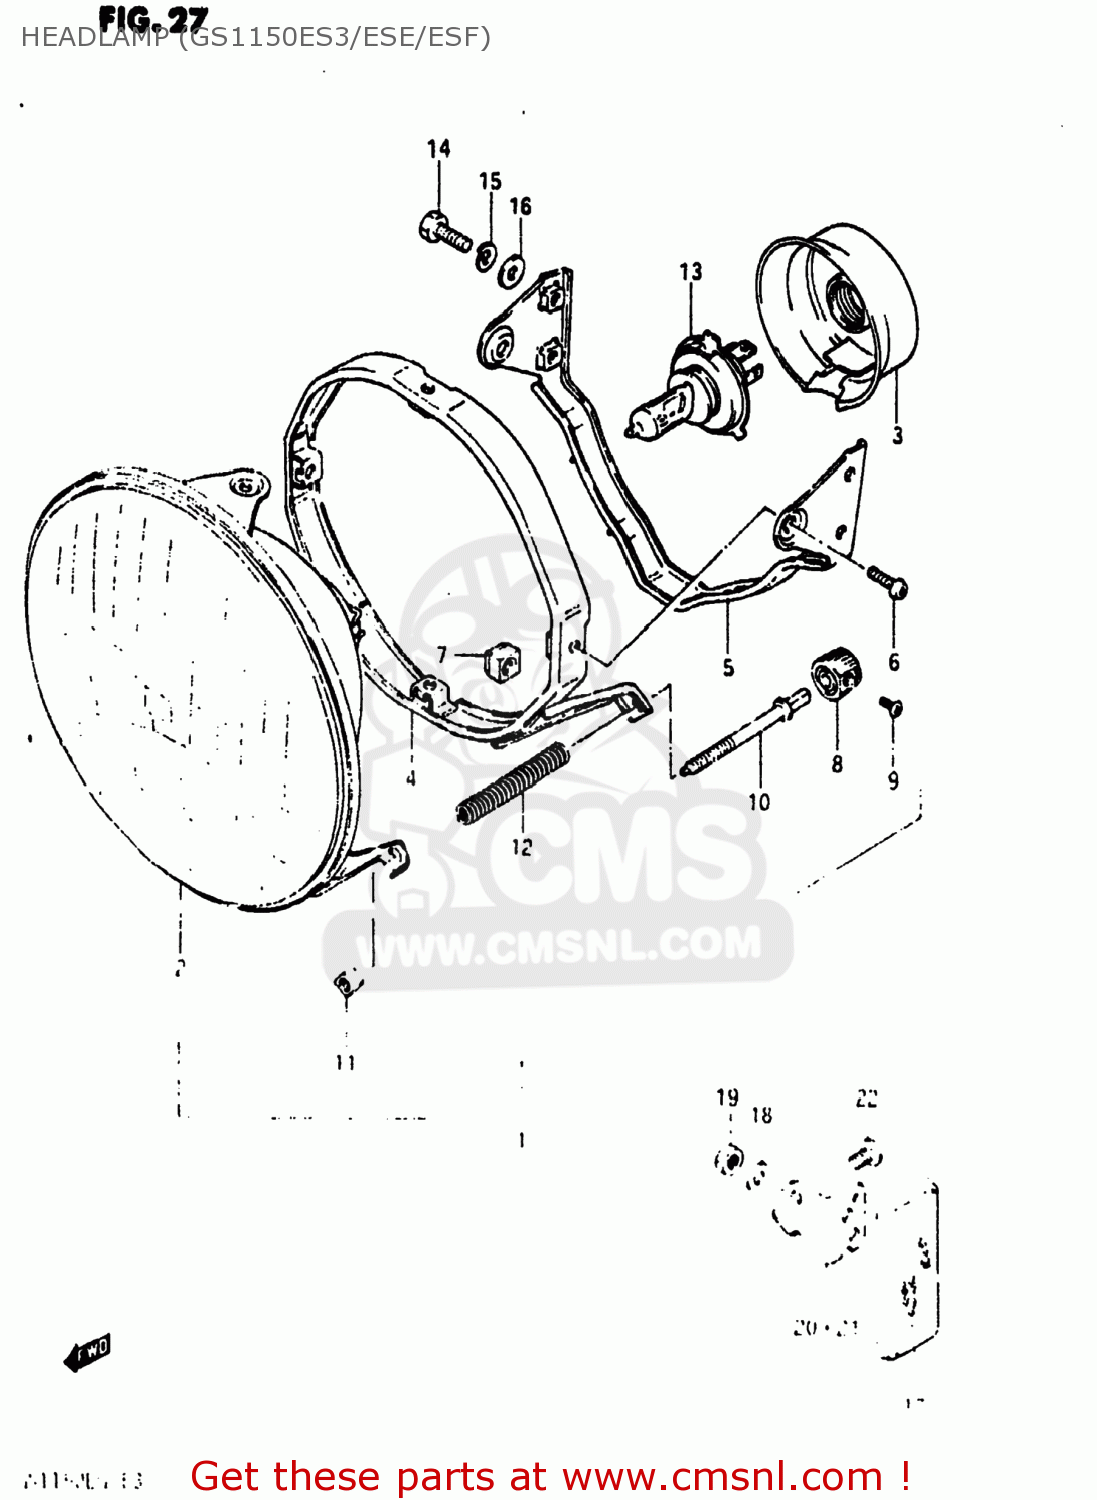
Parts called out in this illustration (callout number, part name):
1	LAMP ASSEMBLY,HEAD
2	UNIT,HEADLAMP
3	COVER,HEADLAMP SOCKET
4	RING,MOUNTING
5	HOUSING,LAMP UNIT
6	SCREW
7	NUT
8	KNOB,ADJUSTER
9	SCREW
10	SCREW,HEADLAMP ADJUST
11	NUT,HEADLAMP ADJUSTER
12	SPRING
13	BULB(12V60/55W,H4)
14	BOLT 6X16
15	WASHER,LOCK
16	WASHER
17	REFLEX REFLECTOR,FR SIDE
18	WASHER,5MM
19	NUT ,5MM
20	BRACKET,FRONT SIDE REFLECTOR
21	BRACKET,FRONT SIDE REFLECTOR
22	SCREW
